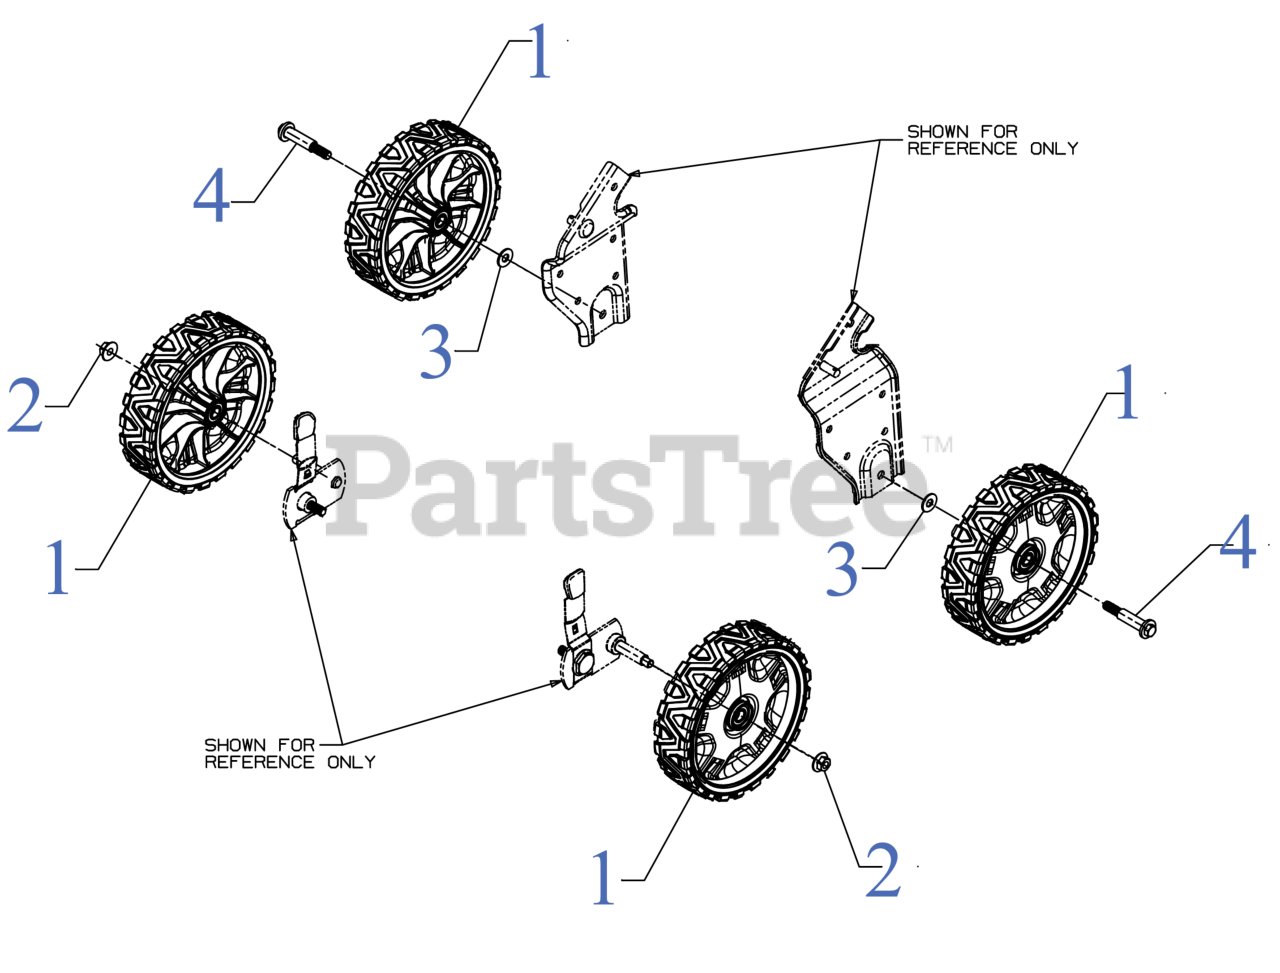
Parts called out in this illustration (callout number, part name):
1	WHEEL ASSEMBLY (8 x 2)
2	FLANGE LOCK NUT
3	BELL WASHER .400 ID x .88 x .060
4	SHOULDER SCREW .496X1.605 3/8-16
